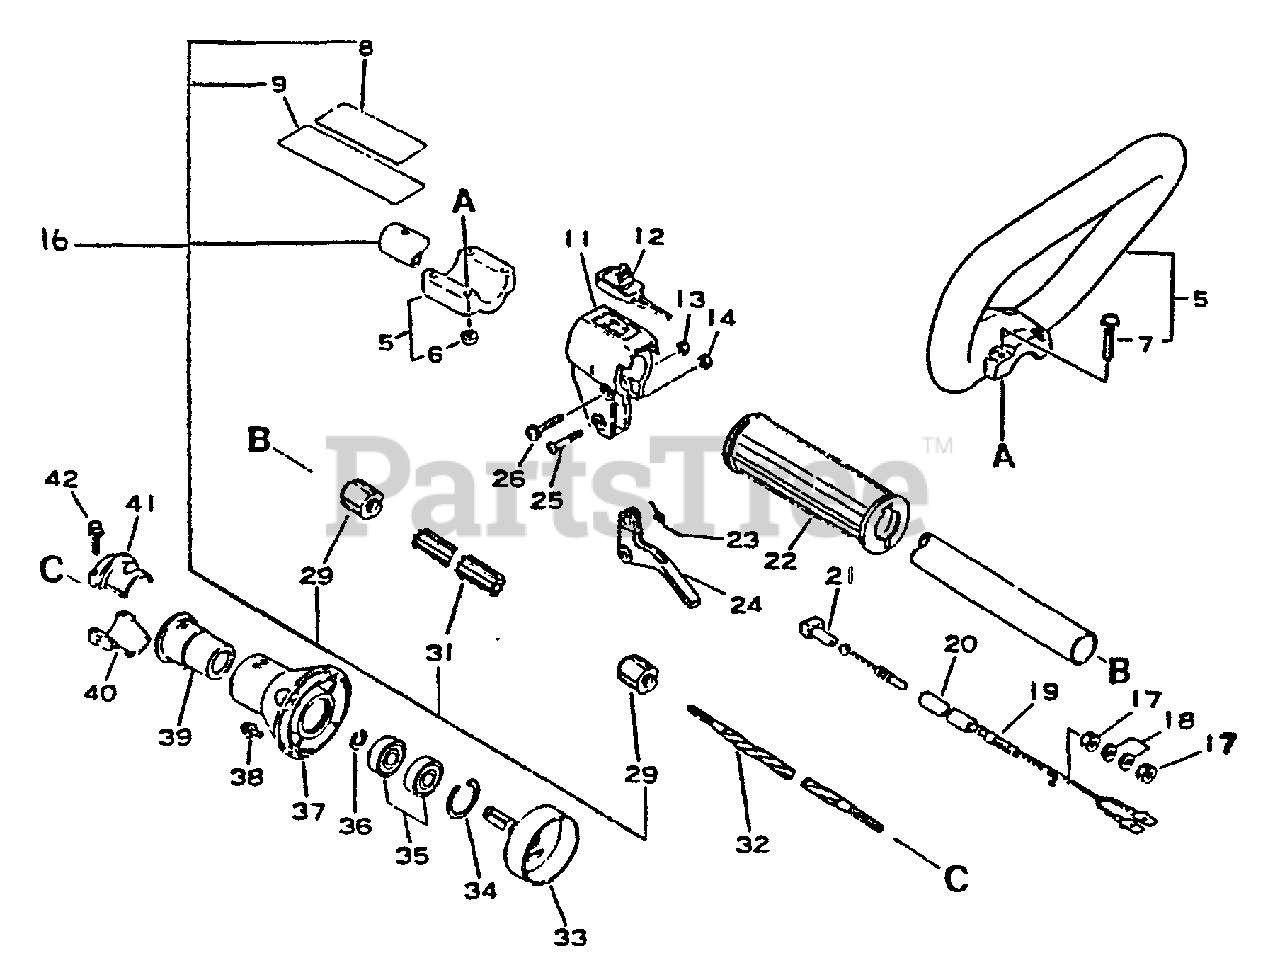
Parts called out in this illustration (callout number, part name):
5	LOOP HANDLE ASSY
7	SCREW - 5X35
8	LABEL - CAUTION
9	LABEL - CAUTION
11	BRACKET, THROTTLE CONTROL
12	IGNITION SWITCH ASSY
14	LOCKNUT - 5
16	MAIN PIPE ASSY
18	WASHER - 6
19	CABLE, THROTTLE
20	TUBE - VINYL
21	GUIDE, CABLE
22	GRIP, HANDLE
23	SPRING, TRIGGER
24	TRIGGER, THROTTLE
25	SCREW - 5X30
26	SCREW - 5X30
31	LINER - FLEXIBLE
32	DRIVESHAFT - FLEXIBLE
33	DRUM, CLUTCH
34	RING, RETAINING - 28
35	BEARING, BALL - 6001
36	RING, RETAINING - 12
37	CASE, CLUTCH - ORANGE
38	SCREW - 5X16
40	CLAMP, MAIN PIPE
41	CLAMP, MAIN PIPE - UPPER
42	BOLT - 5X25
